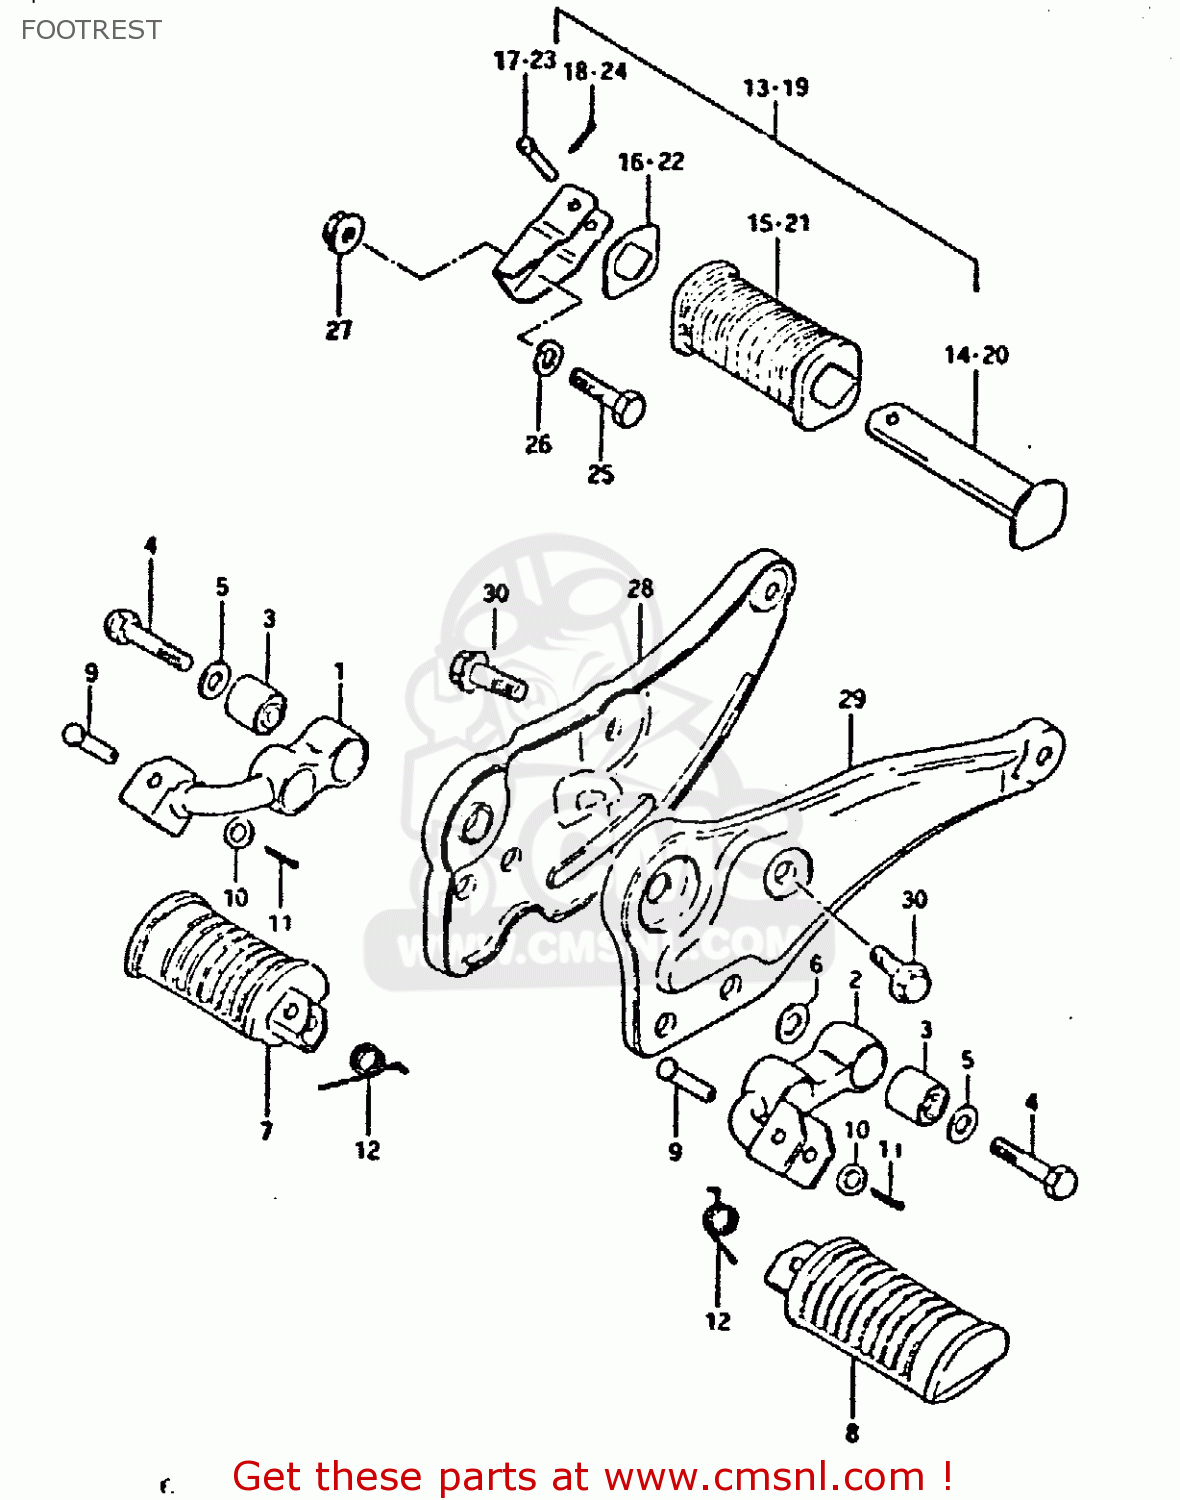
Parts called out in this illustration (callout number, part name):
1	BAR,FRONT FOOTREST
2	BAR,FRONT FOOTREST,LEFT
3	BUSH
4	BOLT(10X50)
5	WASHER
6	WASHER
7	RUBBER,FRONT FOOTREST
8	FOOTREST
9	PIN
10	WASHER
11	PIN
12	SPRING
13	FOOTREST ASSEMBLY,REAR
14	BAR,REAR FOOTREST
15	RUBBER,REAR FOOTREST
16	WASHER,FOOTREST RUBBER
17	PIN
18	PIN
19	FOOTREST ASSEMBLY,REAR,LEFT
20	BAR,REAR FOOTREST,LEFT
21	RUBBER,PILLION FOOTREST
22	WASHER,FOOTREST RUBBER
23	PIN
24	PIN
25	BOLT,M10X1.25X
26	LOCK WASHER
27	NUT
28	BRACKET
29	BRACKET,MUFFLER,LEFT
30	BOLT
